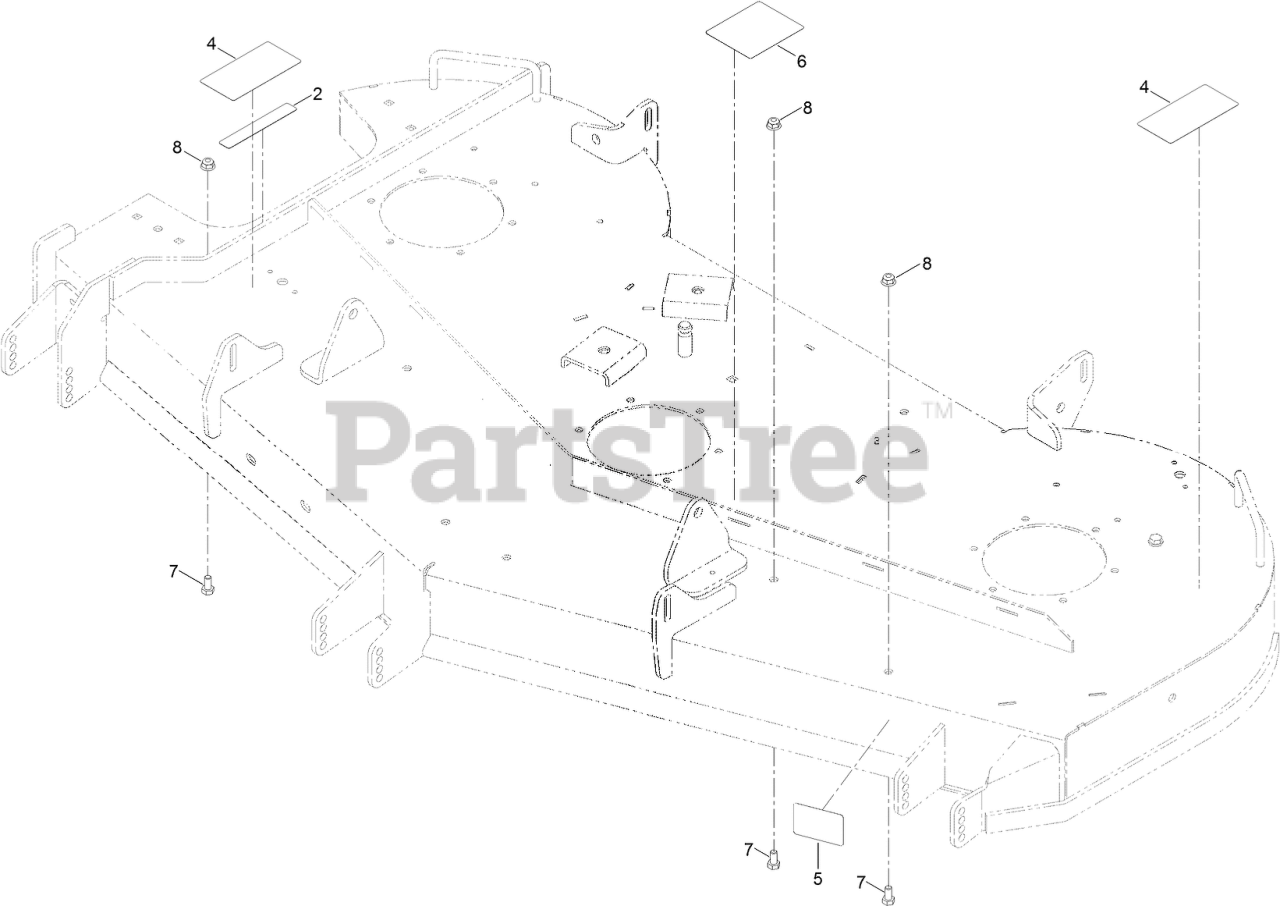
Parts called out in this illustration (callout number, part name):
2	DECAL-DANGER
4	DECAL-DANGER, DECK
5	DECAL-SCALP, ANTI
6	DECAL-ROUTING, BELT
7	SCREW-HH
8	NUT-HF, NI
